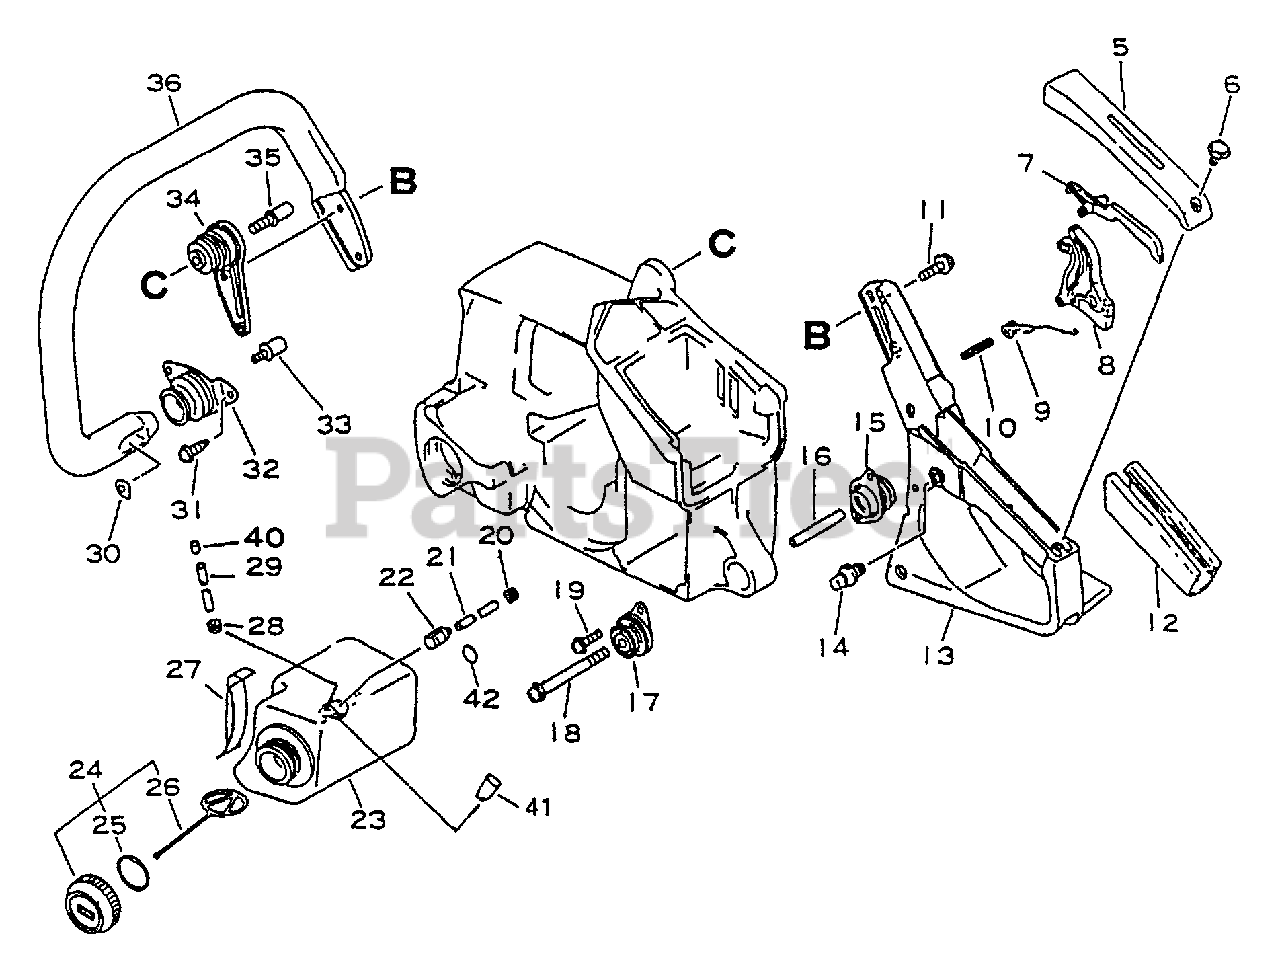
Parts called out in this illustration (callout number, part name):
5	COVER, HANDLE
6	SCREW - 4X14
7	LEVER, TRIGGER LOCKOUT
8	TRIGGER, THROTTLE
9	SPRING, TRIGGER
10	PIN - SPRING -- 4X30
11	SCREW - 5X22
12	GRIP, HANDLE
13	HANDLE - REAR
14	LATCH, THROTTLE
15	CUSHION
18	SCREW - 5X70
19	SCREW - 4X28
21	PIPE - 3X6X230 -- BLACK
22	FILTER, FUEL
23	TANK, FUEL
24	CAP ASSY - ORANGE
25	O-RING - 22
26	CONNECTOR, CAP
27	BRACKET, FUEL TANK
28	GROMMET
29	PIPE - 3X5X130
31	SCREW - 5X20
34	CUSHION
35	SCREW
36	HANDLE - FRONT
41	PLUG
42	CLIP - 6.5
